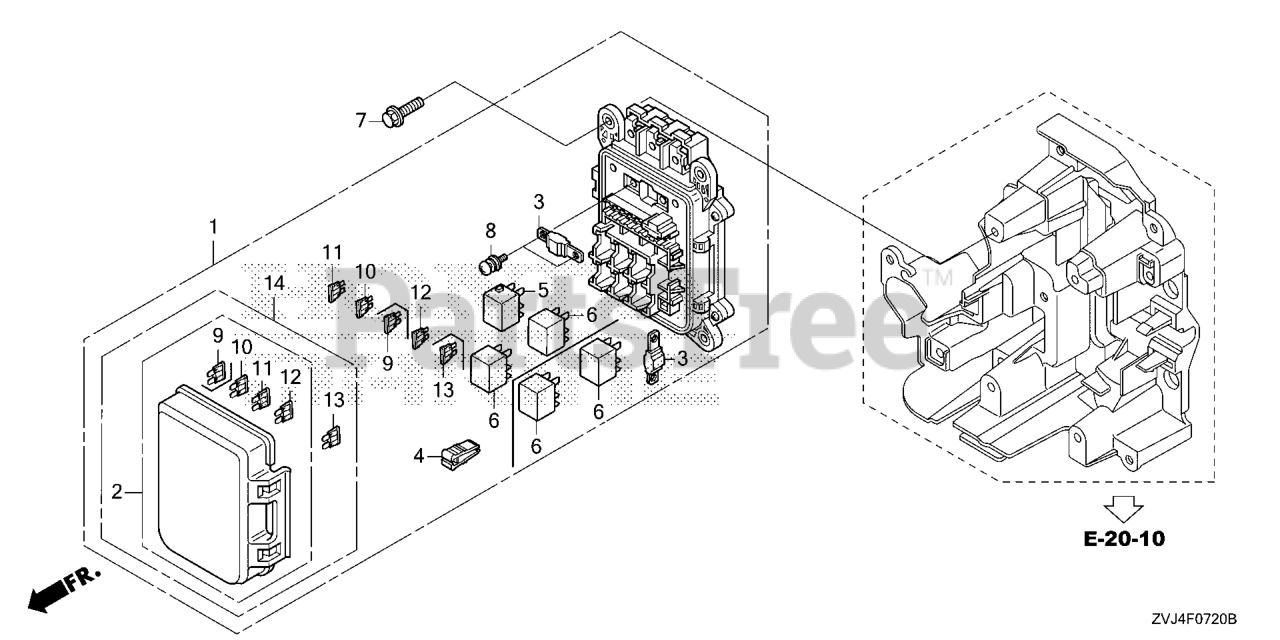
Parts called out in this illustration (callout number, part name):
1	BOX ASSY., JUNCTION
2	COVER COMP, FUSE
3	FUSE, BLOCK (150A)
4	PULLER, MINI FUSE
5	RELAY ASSY., FUEL PUMP (DENSO)
6	RELAY ASSY., POWER (12V-20A) (MICRO ISO 4P)
7	BOLT, FLANGE (6X20)
8	SCREW-WASHER (5X15)
9	FUSE, MINI (7.5A)
10	FUSE, MINI (10A)
11	FUSE, MINI (15A)
12	FUSE, MINI (30A)
13	FUSE, MINI (20A)
14	COVER COMP, FUSE
